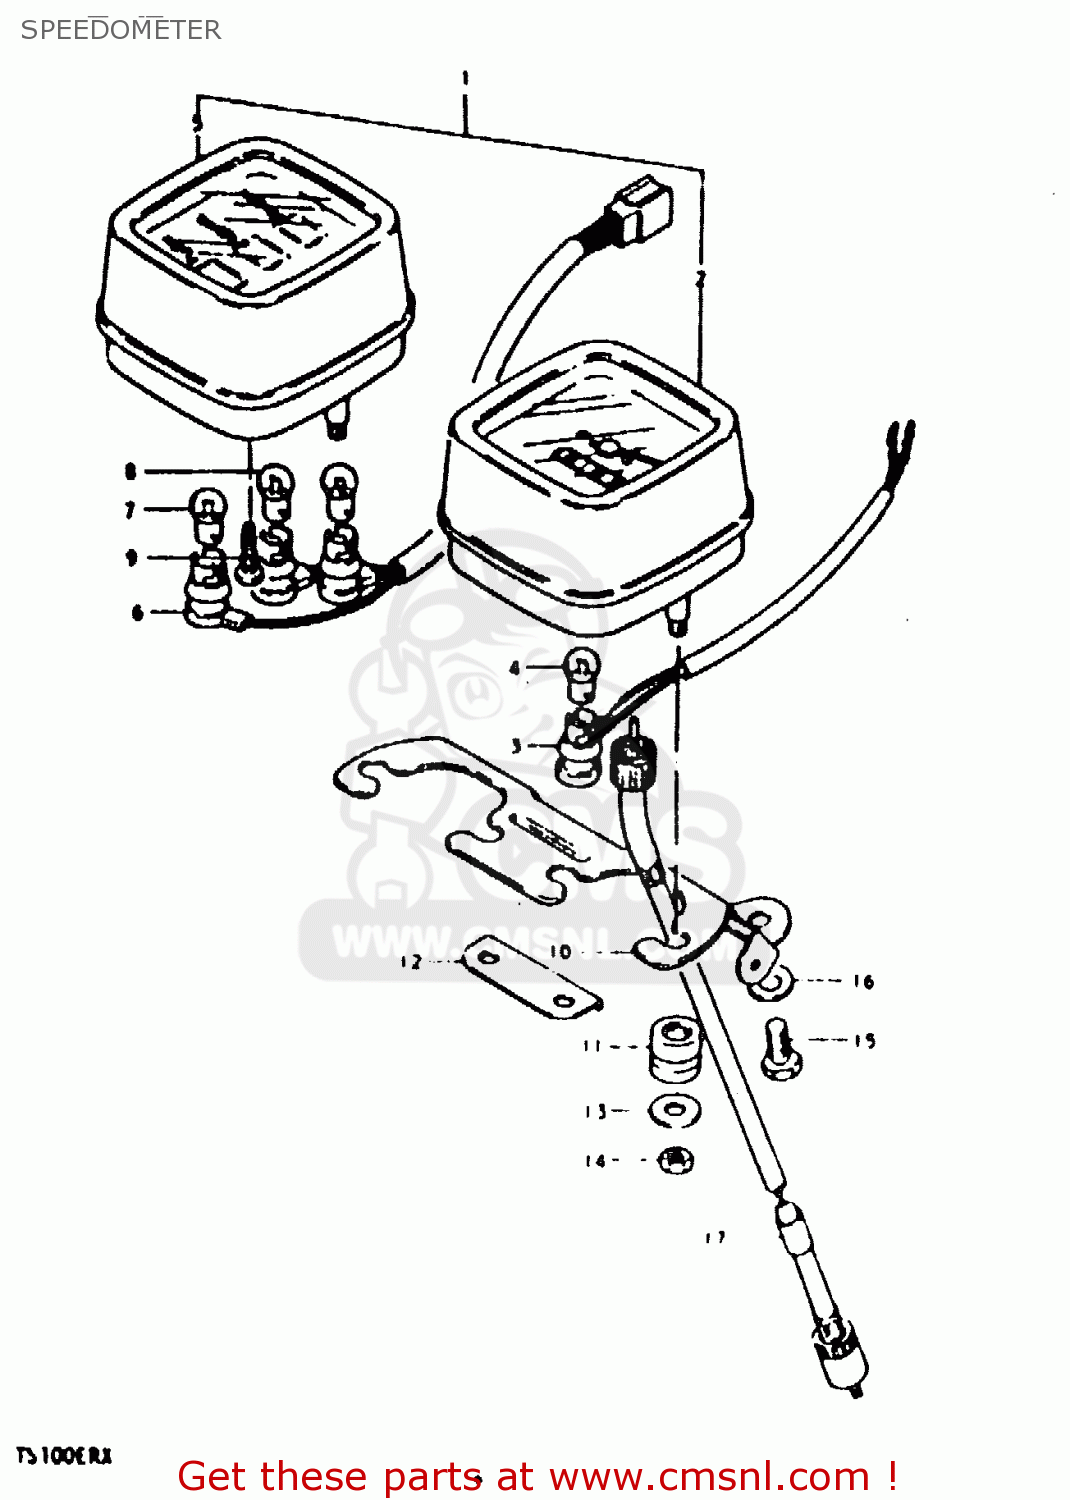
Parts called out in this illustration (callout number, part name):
1	SPEEDOMETER ASSEMBLY
2	SPEEDOMETER ASSEMBLY
3	SOCKET,SPEEDOMETER
4	BULB(6V/3W)
5	CASE,PILOT BULB
6	SOCKET
7	BULB(6V/3W)
8	BULB(6V1.7W,STANLEY,A61A)
9	SCREW
10	BRACKET,SPEEDOMETER
11	CUSHION
12	PLATE,METER CONNECTING
13	WASHER,METER
14	NUT
15	BOLT, UPPER
16	WASHER
17	CABLE ASSY,SPEEDOMETER
